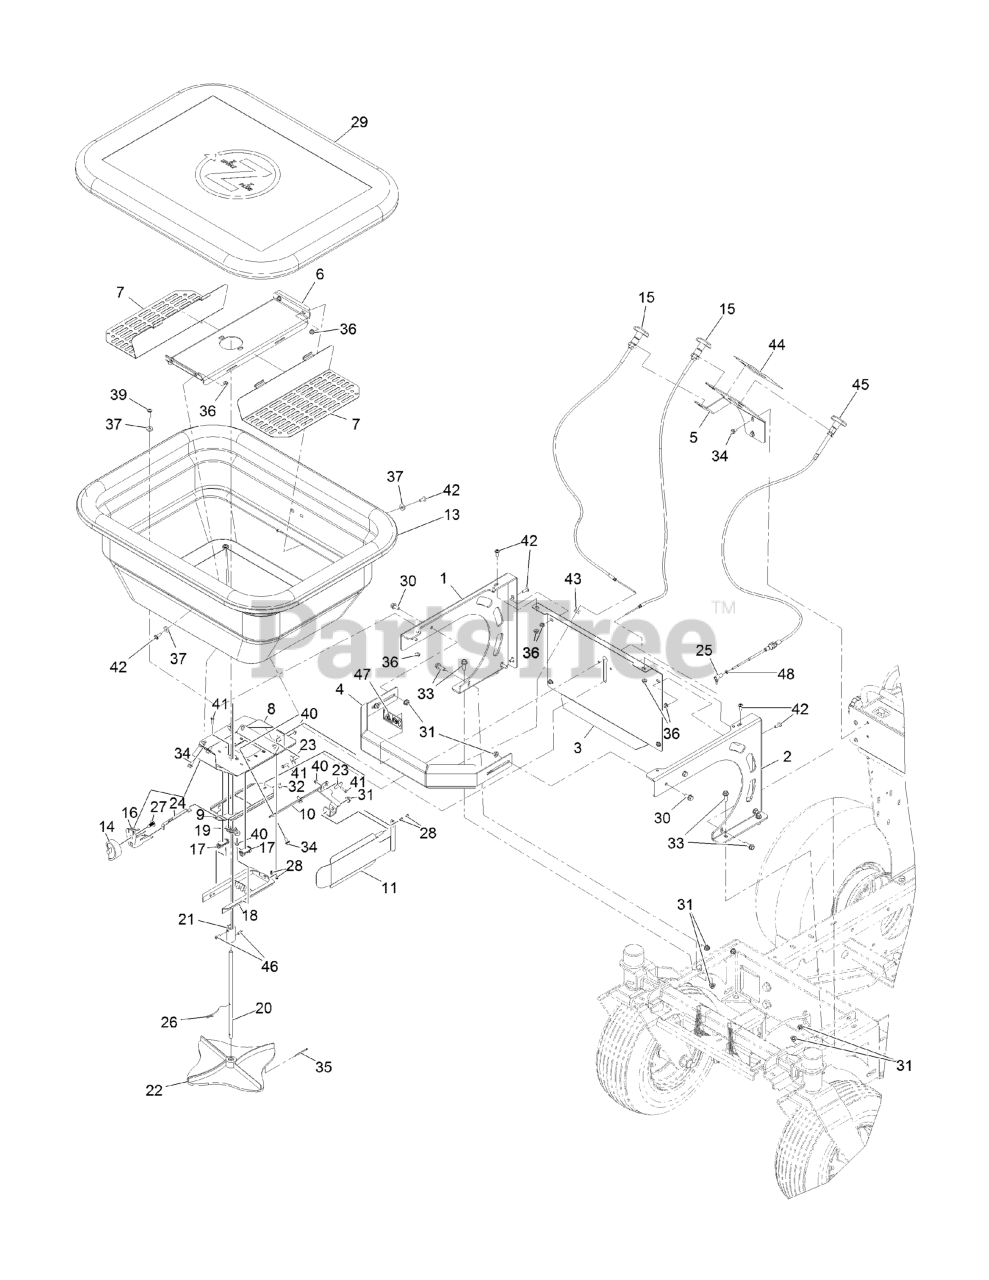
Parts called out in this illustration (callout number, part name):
1	Side-Hopper, Rt
2	Side-Hopper, Lt
3	Backshield-Hopper
4	BUMPER-FRONT, HOPPER
5	Mount-Speedometer
6	PAN-HOPPER, 220
7	SCREEN-HOPPER, 220
8	PLATE-BASE, HOPPER
9	Slide-Door, Hopper
10	Mount-Deflector, Side
11	Deflector-Side, Spreader
13	HOPPER-220LB
14	DIAL
15	CABLE-PUSH/PULL
16	MOUNT-DIAL
17	GUIDE-RATE, GATE
18	DIFFUSER
19	BEARING-FLANGE
20	SHAFT-HOPPER, 220
21	COUPLER-SS
22	SPINNER-SPREADER
23	RETAINER, CABLE
24	LINKAGE-GATE, RATE
25	BALL JOINT-SS
26	WIRE-AGITATOR
27	CLIP
28	RETAINER-CABLE, WIRE
29	COVER-HOPPER, LARGE
30	SCREW-HHF
31	Nut-Hex Flange
32	Nut,NYL Lock,#10-32,ST/ST 18-8
33	SCREW-HHF
34	SCREW-HHF
35	PIN-COTTER
36	Nut-Hex Flange
39	Screw-Hsbhf
40	Nut-Hex Flange
41	SCREW-HH
42	Screw-Hsbhf
43	Grommet-Rubber
44	DECAL-HOPPER CONTROL
45	CABLE-PUSH/PULL
46	Screw-SQH
47	Decal-Dismemberment Hazard
48	Nut,Hex Jam Mch Scr,10-32,Sst
